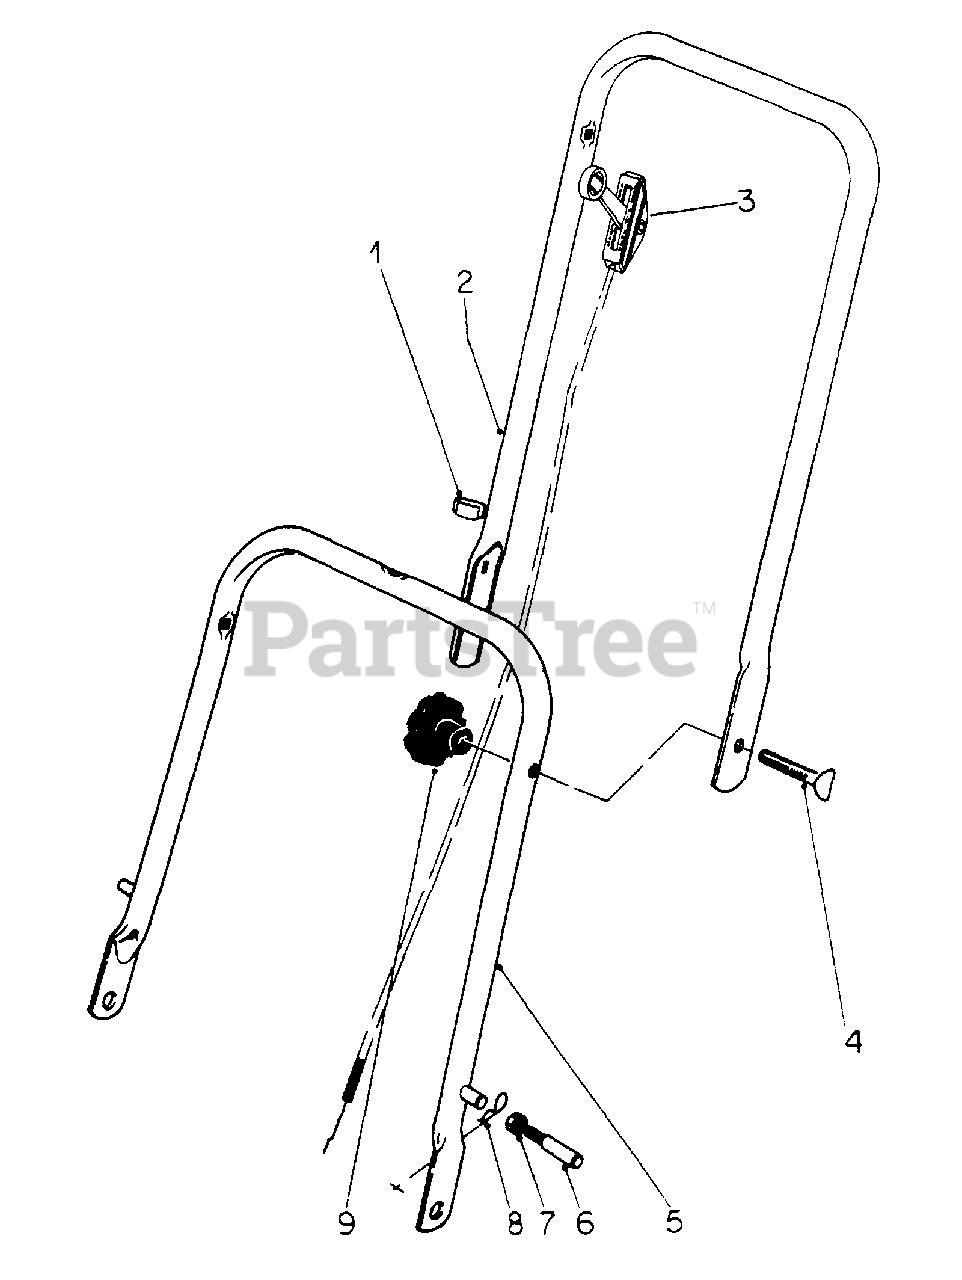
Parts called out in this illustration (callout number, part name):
2	HANDLE, UPPER
3	CONTROL, THROTTLE
4	BOLT, HANDLE
5	HANDLE, LOWER
6	PIN, HANDLE
7	NUT, 1/4-20 LOCK
8	PIN, HAIR PIN COTTER
9	KNOB, HANDLE
